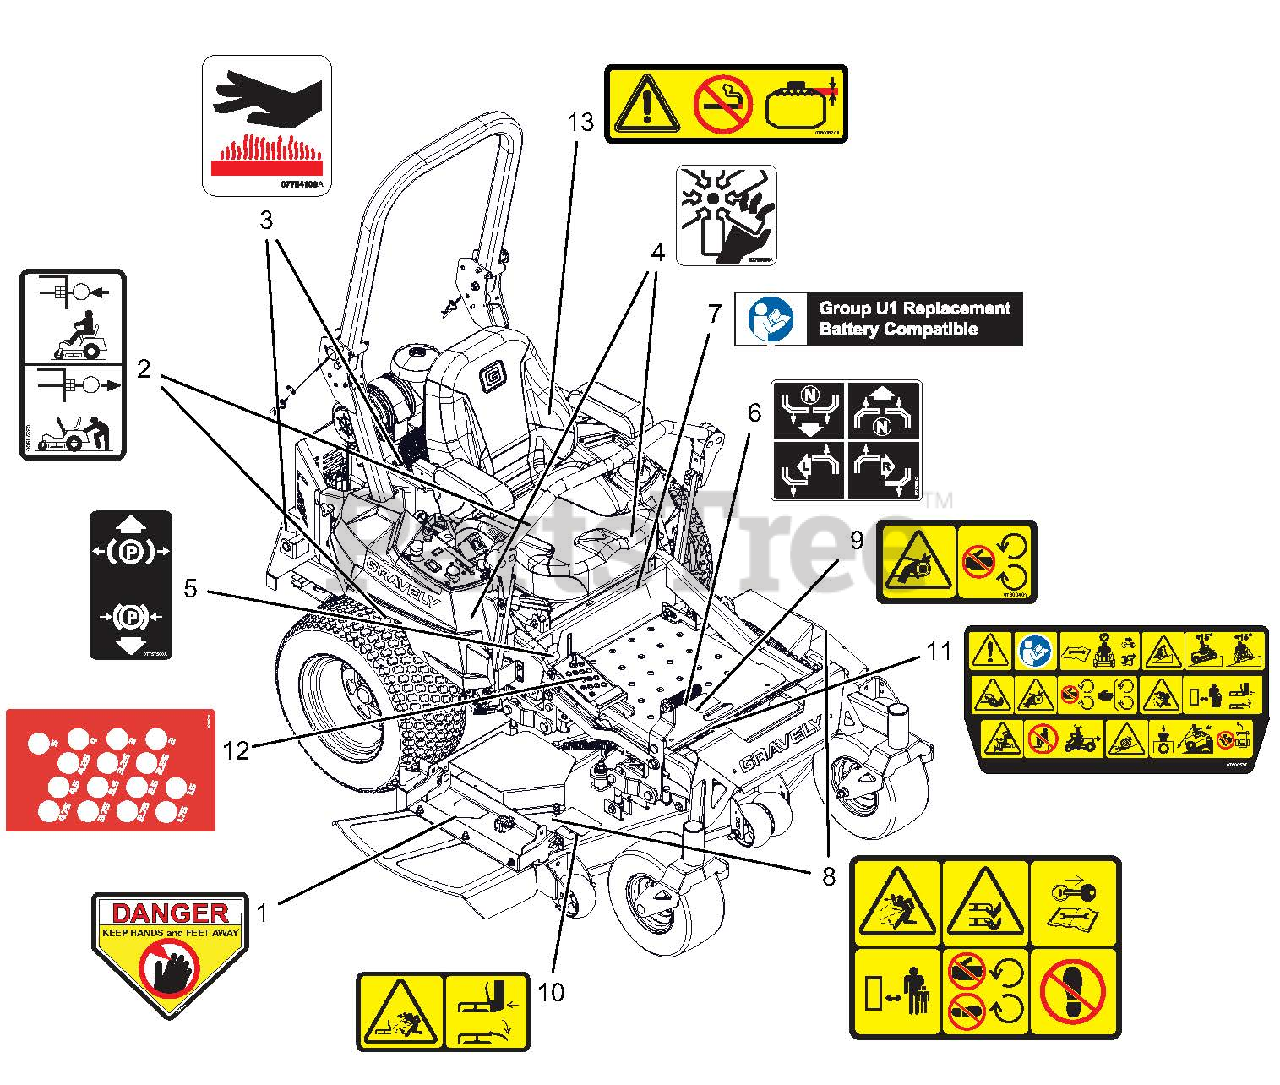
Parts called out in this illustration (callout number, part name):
1	DECAL, DANGER
2	DECAL, TRANSMISSION DISCONNECT
3	DECAL, HOT SURFACE
4	DECAL, DANGER FAN
5	DECAL, PARKING BRAKE LEVER
6	DECAL, INSTRUCTIONAL-STEERING
7	DECAL, U1 BATTERY REPLACEMENT
8	DECAL, SAFETY - MOWER DECK
9	DECAL, SAFETY - GUARDING
10	DECAL, SAFETY - DECK GUARDING
11	DECAL, MAIN SAFETY
12	DECAL - HOC
13	DECAL, FUEL WARNING
